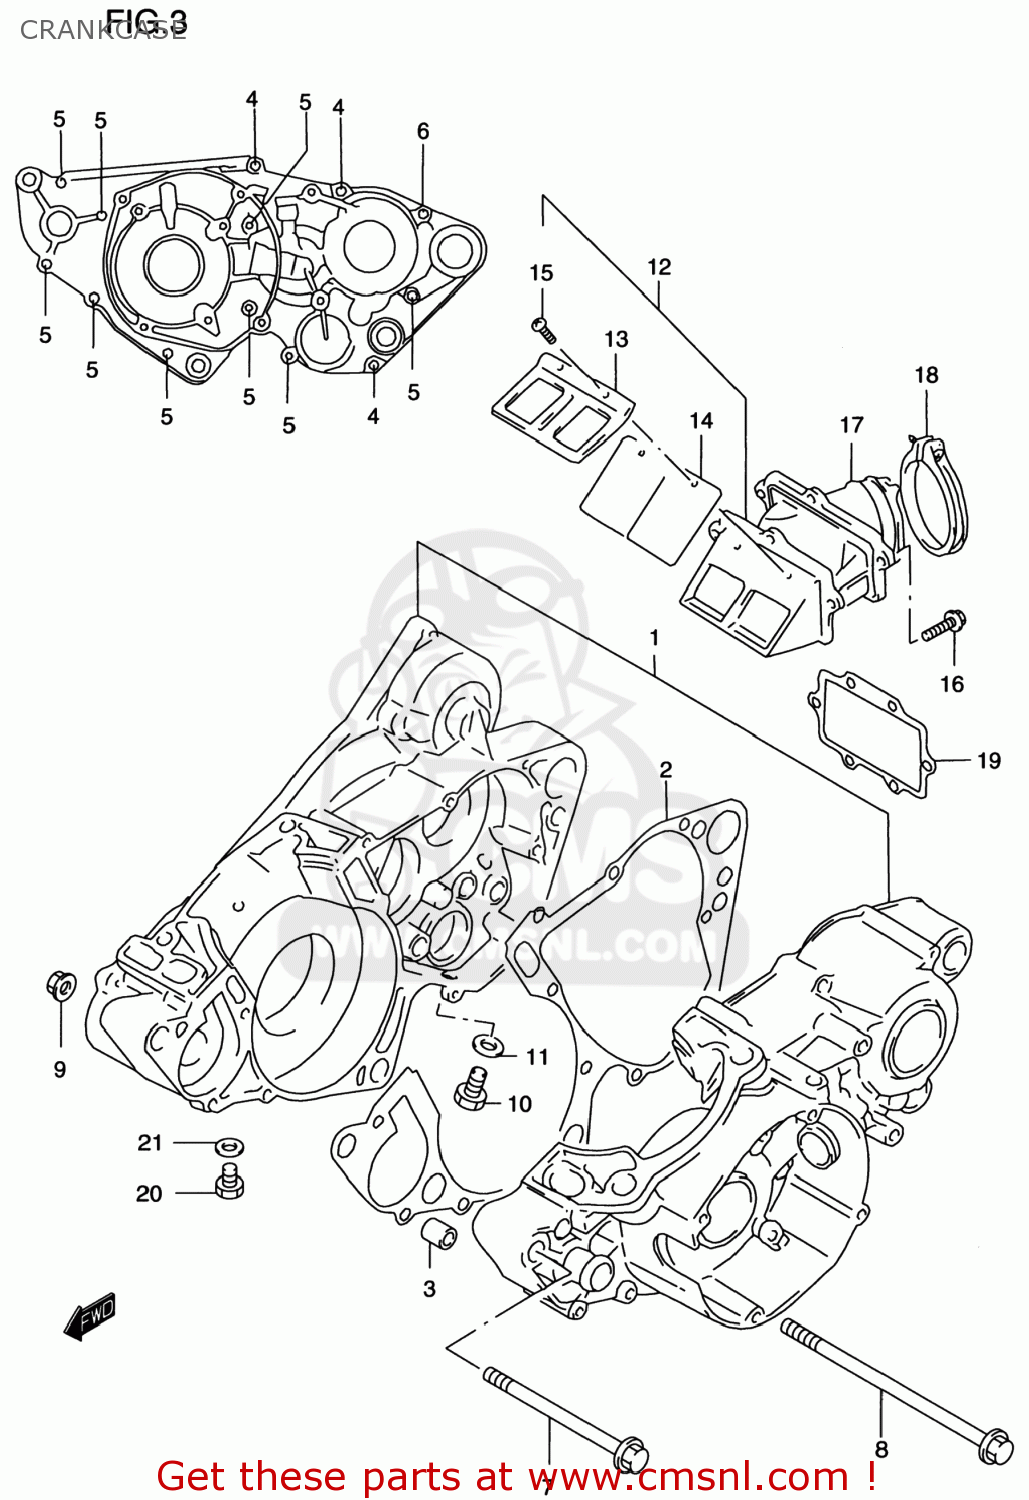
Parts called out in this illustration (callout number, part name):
1	CRANKCASE SET
2	GASKET,CRANKCASE
3	PIN(13X10.4X20)
4	BOLT
5	BOLT
6	BOLT
7	BOLT(10X105)
8	BOLT(10X140)
9	NUT
10	Bolt
11	GASKET(12.1X16.2X3.7) (NAS)
12	VALVE ASSY,REED
13	STOPPER,REED VALVE
14	VALVE,REED
15	SCREW
16	SCREW
17	PIPE,INTAKE
18	CLAMP
19	GASKET,REED VALVE
20	BOLT,DRAIN
21	GASKET 8.2X14X1 (NAS)
